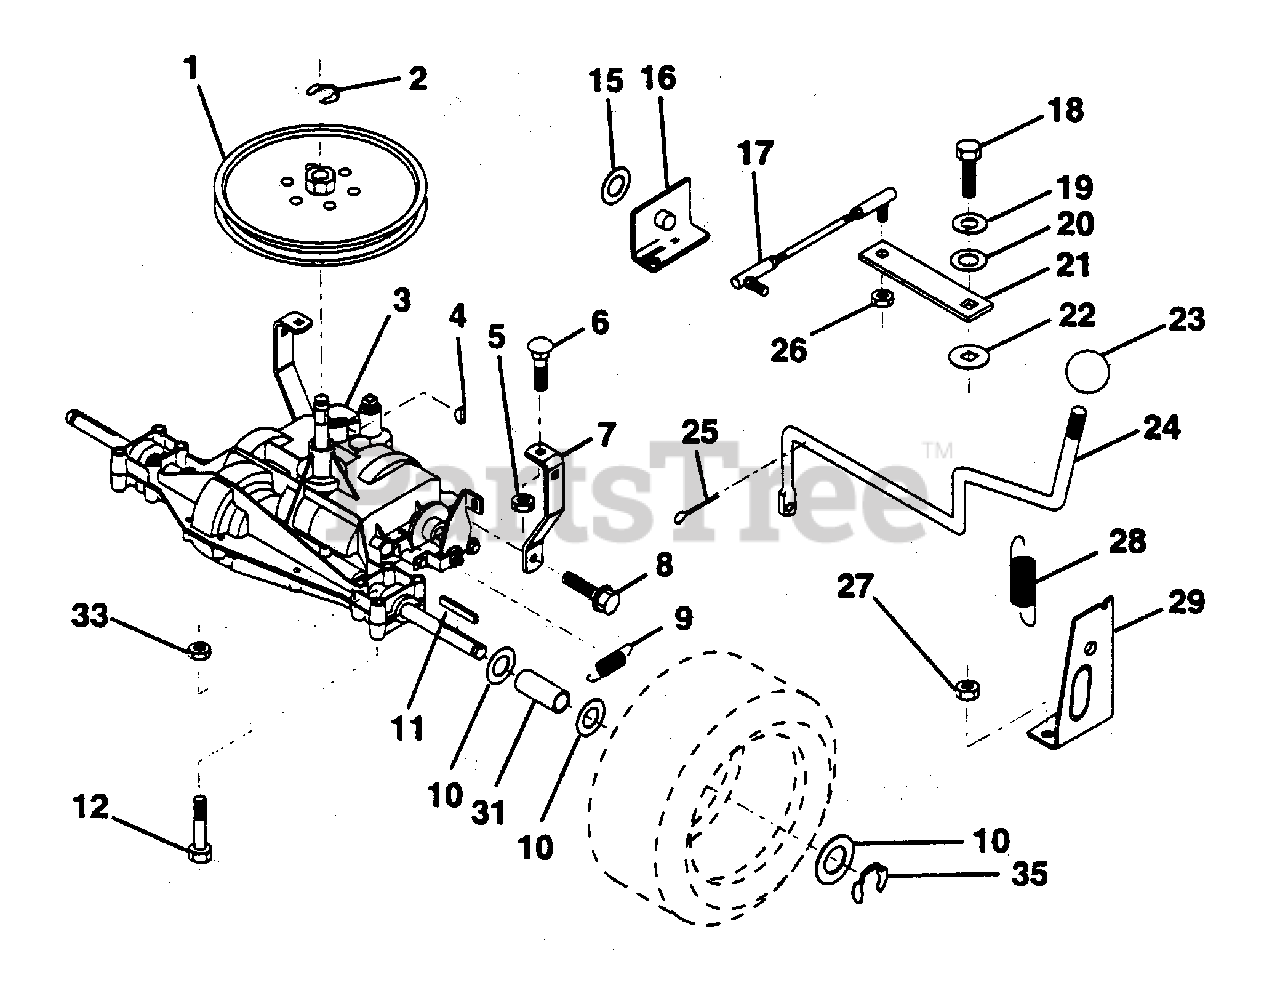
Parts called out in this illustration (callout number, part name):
2	Ring, Retainer
3	Transaxle, Dana 5 Spd. Model No. 4360-78
4	Key, Woodruff #9
5	Locknut, Hex W/Ins. 5/16-18
6	Bolt, Carriage 5/16-18 UNC x 3/4
7	Strap, Torque
8	Screw 5/16-18 x 3/4
9	Spring, Brake
10	Washer 25/32 x 1-1/4 x 16 Ga.
12	Bolt, Fin Hex 3/8-16 UNC 2-3/4
15	Washer 17/32 x 1 x 16 Ga.
16	Support Handle Shift LH
18	Bolt, Fin Hex 1/4-28 UNF x 3/4 Gr. 8
19	Washer, Lock 1/4
20	Washer 9/32 x 3/4 x 10 Ga.
22	Washer, Shift Plate
23	Knob, Rd 1/2-13
25	Pin, Cotter 1/8 x 1
26	Locknut 5/16-24 UNF
27	Nut, Keps 5/16-18
28	Extension, Spring
29	Support Handle Shift RH
33	Locknut Hex W/Wsh 3/8-16
